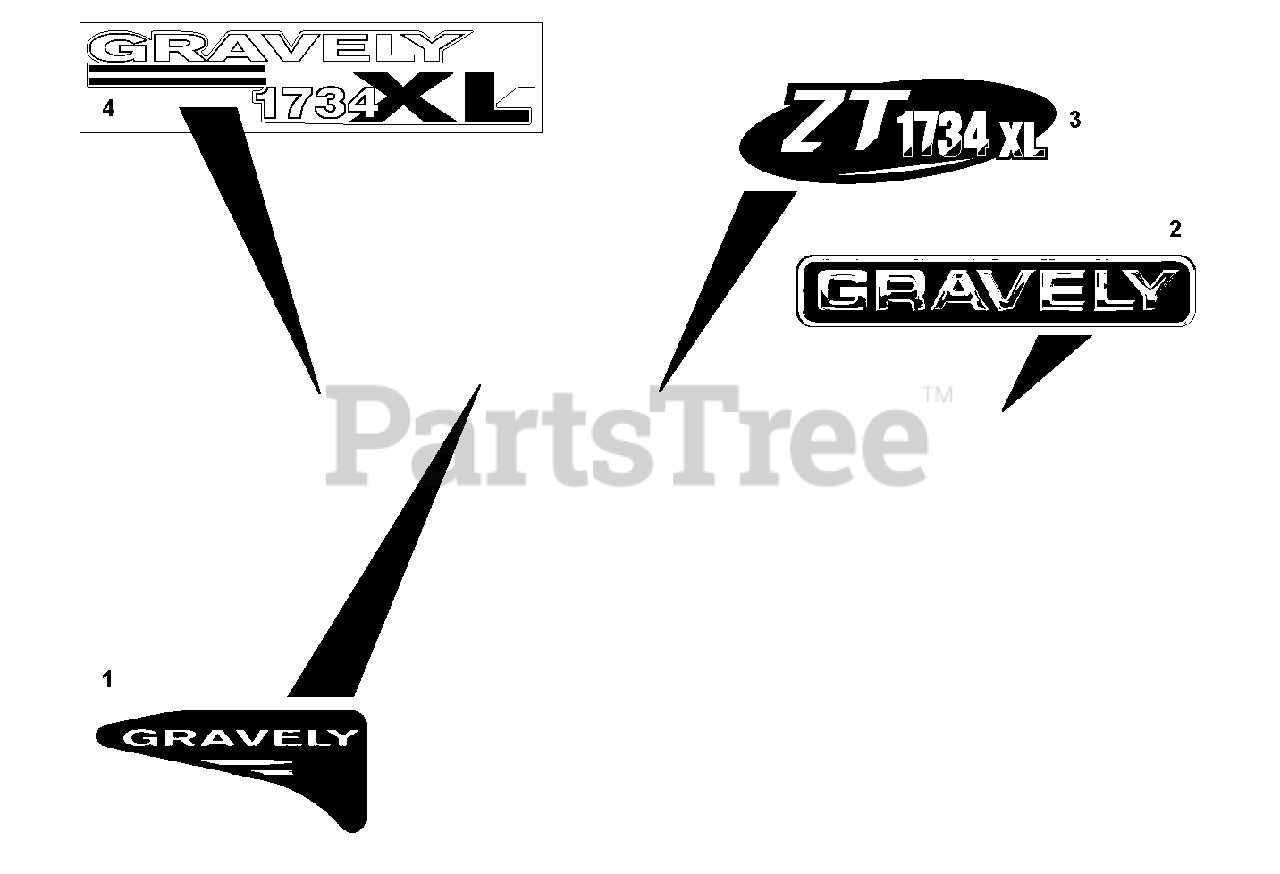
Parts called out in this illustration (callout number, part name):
1	Decal, Gravely ZT XL RH Fender
2	Decal, Gravely Logo
3	Decal, Gravely 1734 ZT XL
4	Decal, Gravely ZT XL Hood
